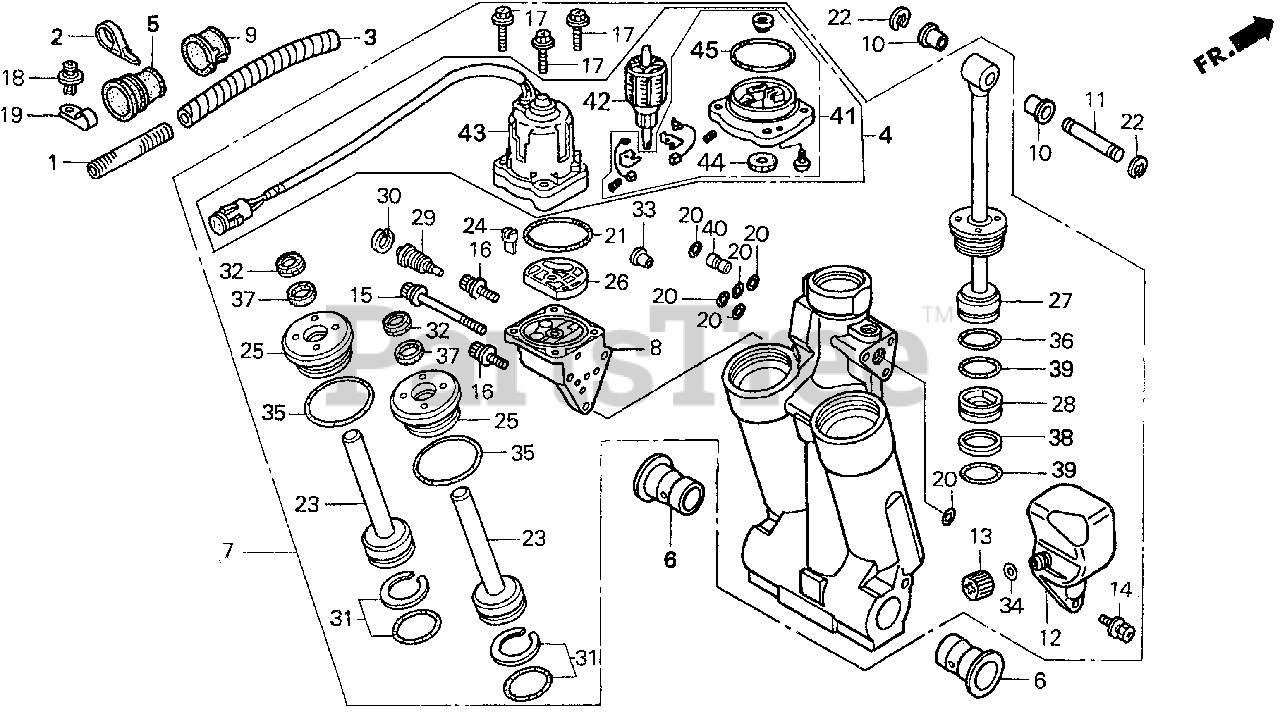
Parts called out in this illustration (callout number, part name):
1	TUBE, CORRUGATED (10MM)
3	TUBE, SPIRAL (12X14.6)
4	MOTOR ASSY., POWER TILT
5	GROMMET, CASE (LOWER) (C)
6	BUSH, SWIVEL CASE
7	TRIM-TILT ASSY., POWER *NH283* (STIN GRAY)
7	TRIM-TILT ASSY., POWER
8	PUMP ASSY.
9	BUSH, MOTOR CODE
10	BUSH, CYLINDER (LOWER)
11	PIN, CYLINDER (UPPER)
12	TANK, OIL
13	CAP, OIL TANK
14	BOLT, RECESSED
15	BOLT A, SOCKET
16	BOLT B, SOCKET
17	BOLT, HEX.
18	SCREW, RIVET (5X10)
20	O-RING
22	E-RING (15MM)
23	ROD, PISTON (B)
24	JOINT, DRIVE
25	GUIDE, ROD
26	FILTER (B)
27	ROD, PISTON
28	PISTON, FREE
29	VALVE, MANUAL
30	CIRCLIP (INNER)
31	O-RING SET
32	O-RING SET
33	COLLAR, ORIFICE
34	O-RING
38	RING, BACK-UP
41	BRACKET ASSY.
42	ARMATURE
43	YOKE ASSY.
45	O-RING
